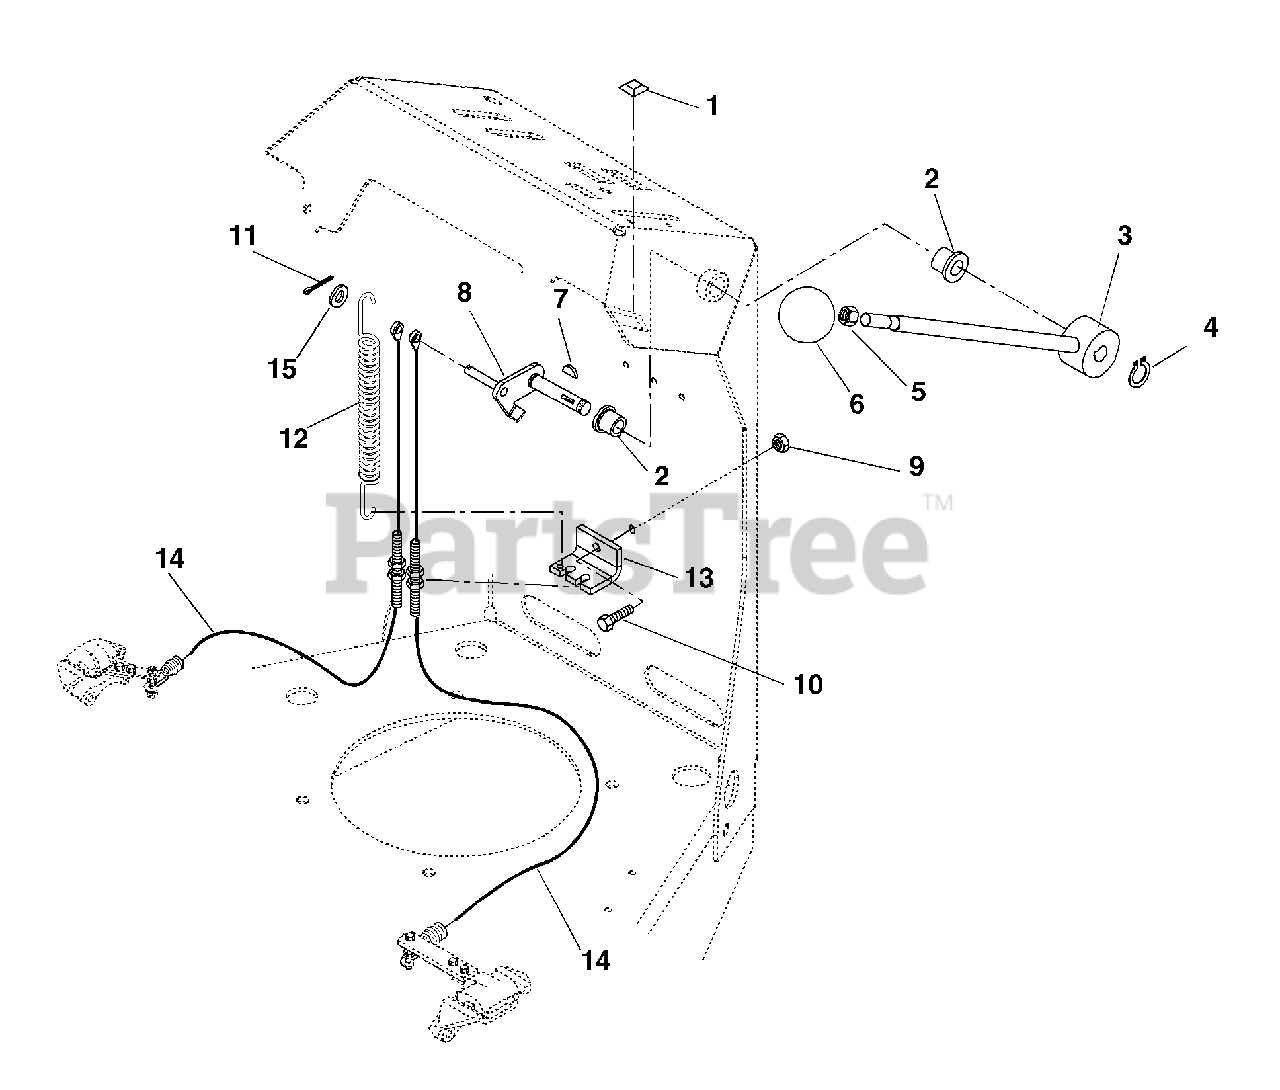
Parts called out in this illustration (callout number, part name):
1	Stop
2	Bushing-Flange .50 x .75 x .75 x 1.00
3	Weldment, Parking Brake Lever
4	Ring-Retaining-External .50 x .05
5	Nut-Hex-Jam .38-16
6	Knob-Steering Lock
7	Key-Woodruff .13 x .63
8	Weldment, Shaft Brake Activation
9	Nut-Locking-Nylon .31-18
10	Bolt-Hex .31-18 x 1.00 Grade 5
11	Pin-Cotter .09 x .75
12	Spring-Tension .062 x .56 x 8.0
13	Bracket, Cable
14	Cable, Parking Brake
15	Washer-Flat-Steel .344 x .688 x .065
